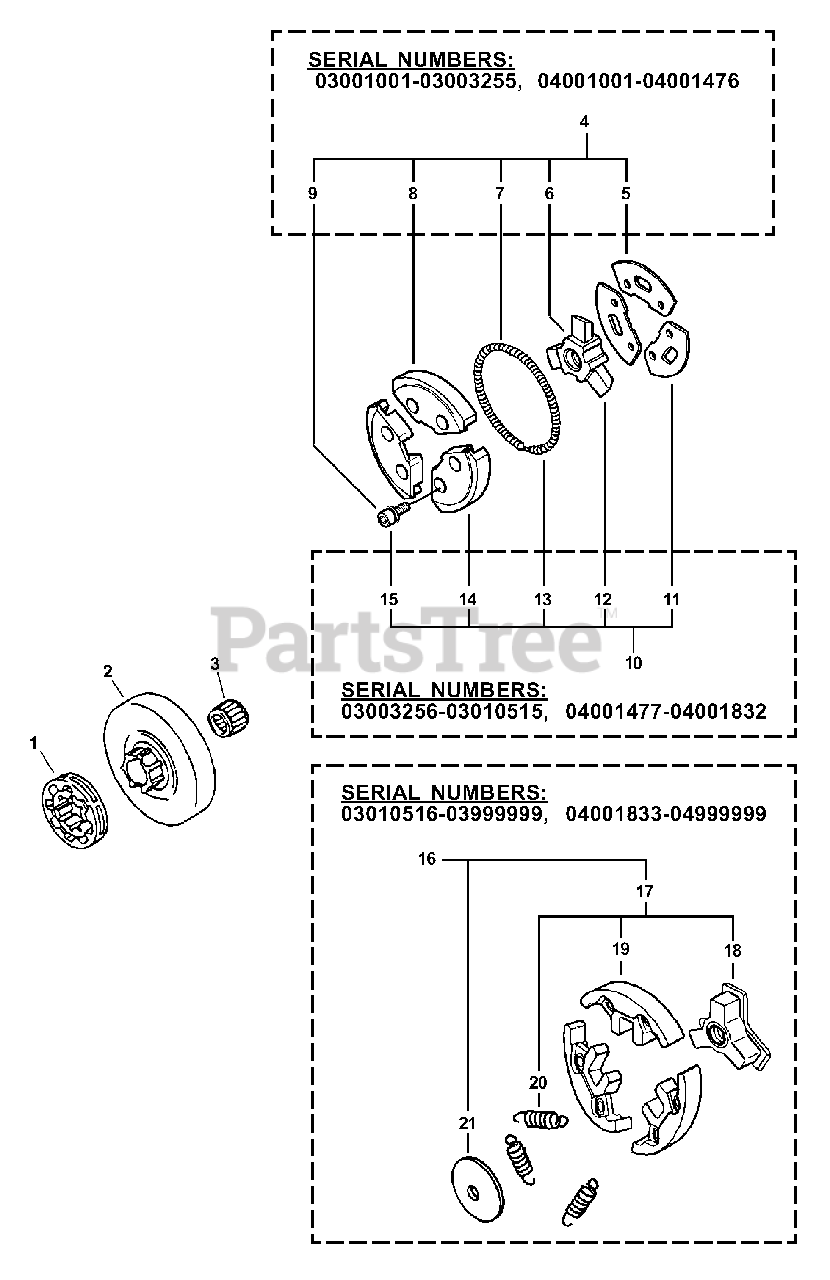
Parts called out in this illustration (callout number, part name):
1	SPROCKET, RIM 3/8"×7T
2	DRUM, CLUTCH
3	BEARING, NEEDLE
4	CLUTCH ASSY
5	PLATE, CLUTCH
6	HUB, CLUTCH
7	SPRING, TENSION
8	CLUTCH SHOE SET
9	BOLT 4×6
10	CLUTCH ASSY
11	PLATE, CLUTCH
12	HUB, CLUTCH
13	SPRING, TENSION
14	CLUTCH SHOE SET
15	BOLT 4×6
16	CLUTCH ASSY
17	CLUTCH ASSY
18	HUB, CLUTCH
19	SHOE SET, CLUTCH (3PCS)
20	SPRING, TENSION
21	PLATE, CLUTCH
